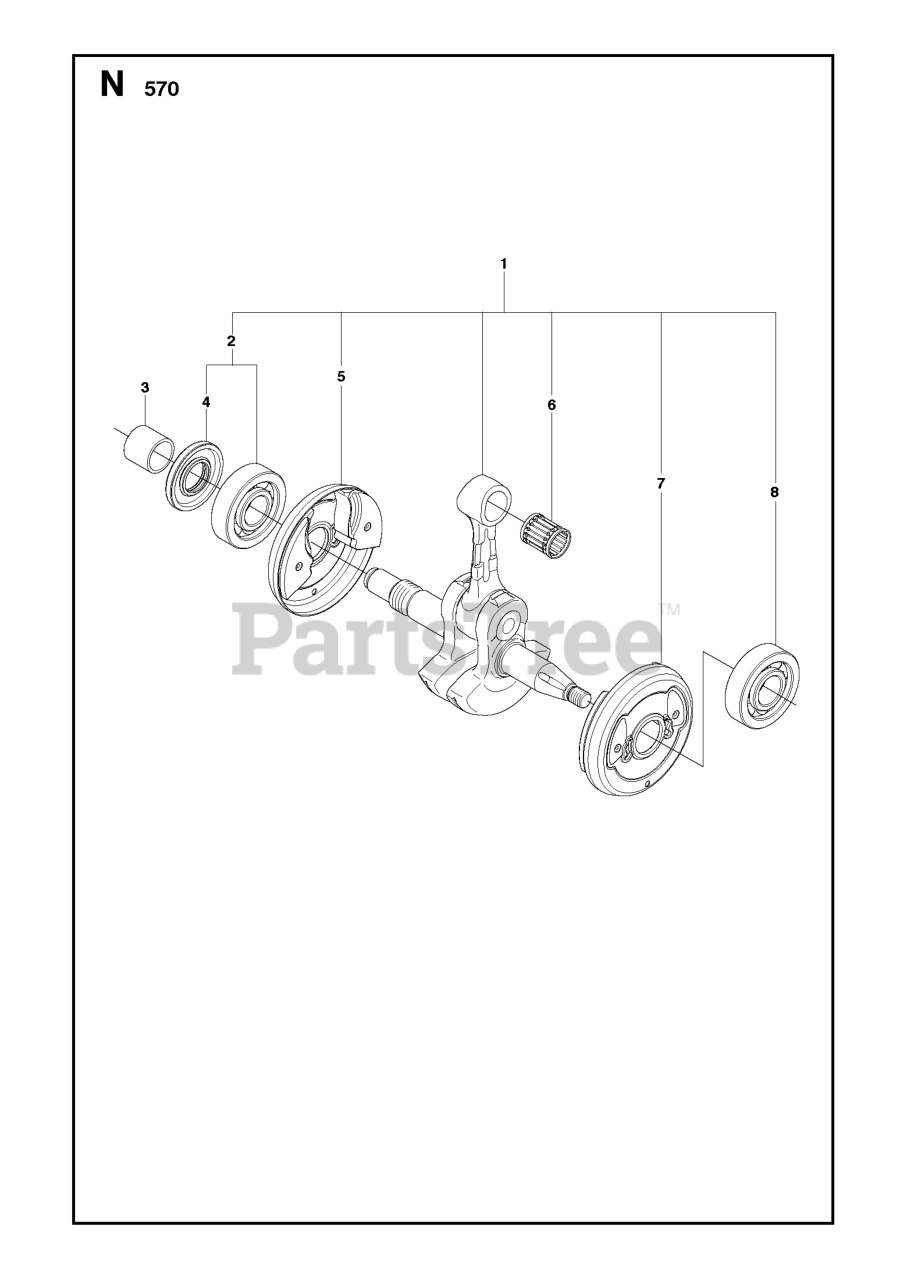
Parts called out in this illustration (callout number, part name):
1	CRANKSHAFT ASSY
2	BALL BEARING
4	RADIAL SEAL
6	SUPPORT BUSHING
8	BALL BEARING
